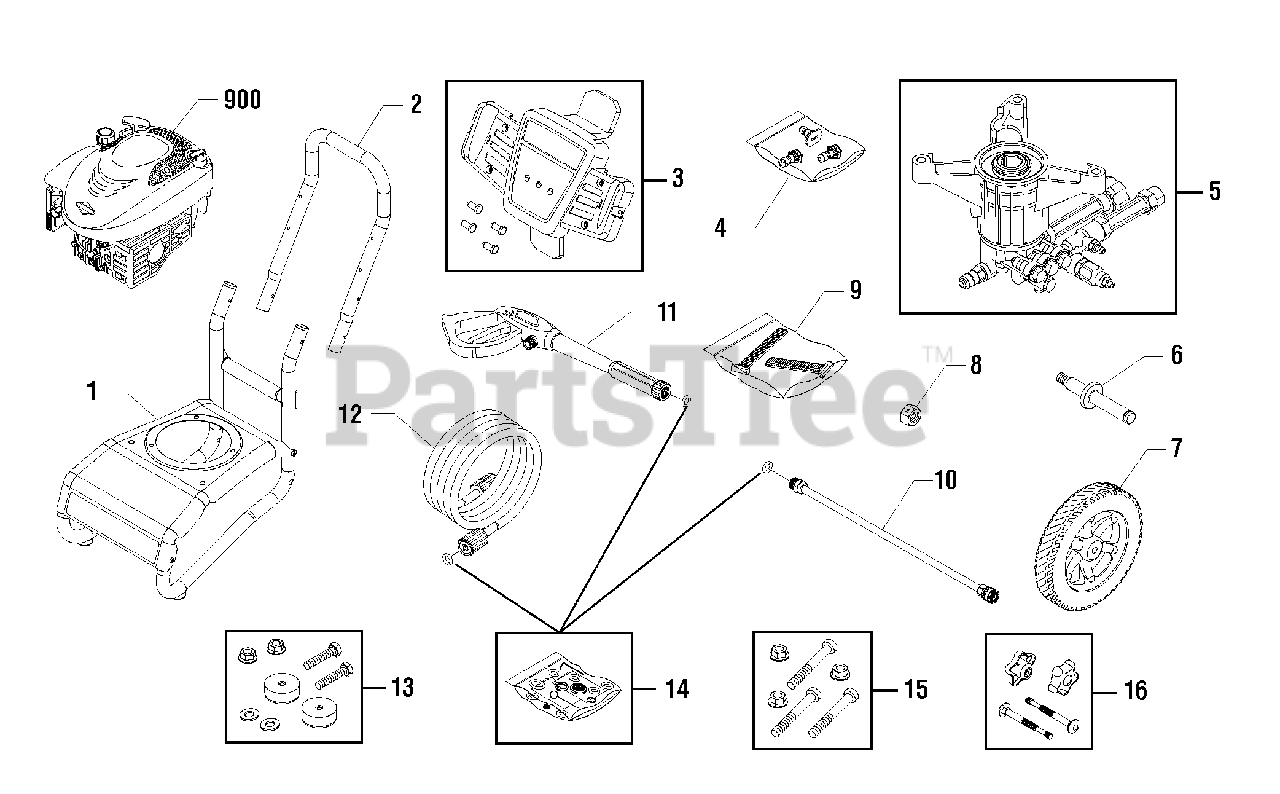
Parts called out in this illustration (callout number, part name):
1	BASE
10	EXTENSION, QC
11	GUN
12	HOSE
13	MOUNT, Vibration
15	KIT, Hardware, Pump Mounting
